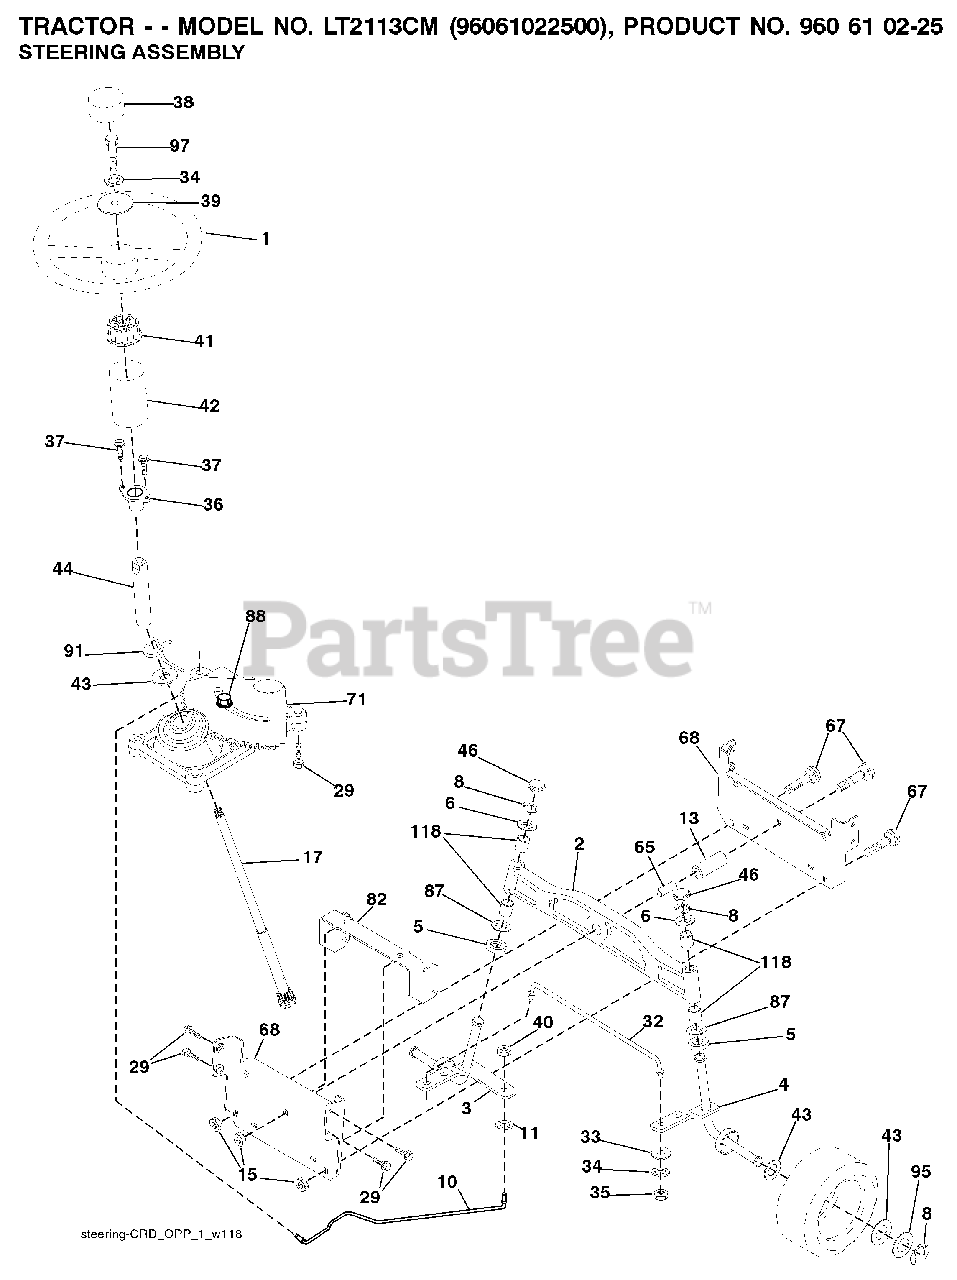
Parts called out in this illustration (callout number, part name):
2	AXLE ASSY FRONT
3	SPINDLE.ASM.LH.15"TIRES
4	SPINDLE.ASM.RH.15"TIRES
8	RING CLIP
10	DRAGLINK.15".TIRES.2001
11	WASHER, LOCK 3/8
13	TUBE, PIVOT AXLE
15	NUT
17	SHAFT STEERING SPLINE
29	SCREW, 3/8-16X3/4
32	ROD.ASM.TIE.BALL.JOINT.NOVAN
33	WASHER M
34	LOCKWASHER
35	NUT, CROWNLOCK
36	BUSHING, STEERING
39	WASHER.11/32
40	NUT CROWNLOCK 3/8-24
41	ADAPTER, WHEEL STNG..
42	BOOT.STEERING.SHAFT.BLACK
44	SHAFT.EXTEN.STRG.SPLINE
46	CAP.SPINDLE
65	SPACER BRACE AXLE
67	BOLT CARRIAGE
68	BRACE.AXLE.15"TIRES
71	STEERING ASM
82	BRACKET.SUSP.CHASSIS.FRONT.15
87	WASHER, FLAT .781 X 1 1/2"
88	BOLT, SHOULDER 7/16-20
91	CLIP.STEERING
95	WASHER.HARDENED
118	BUSHING, AXLE CAST
